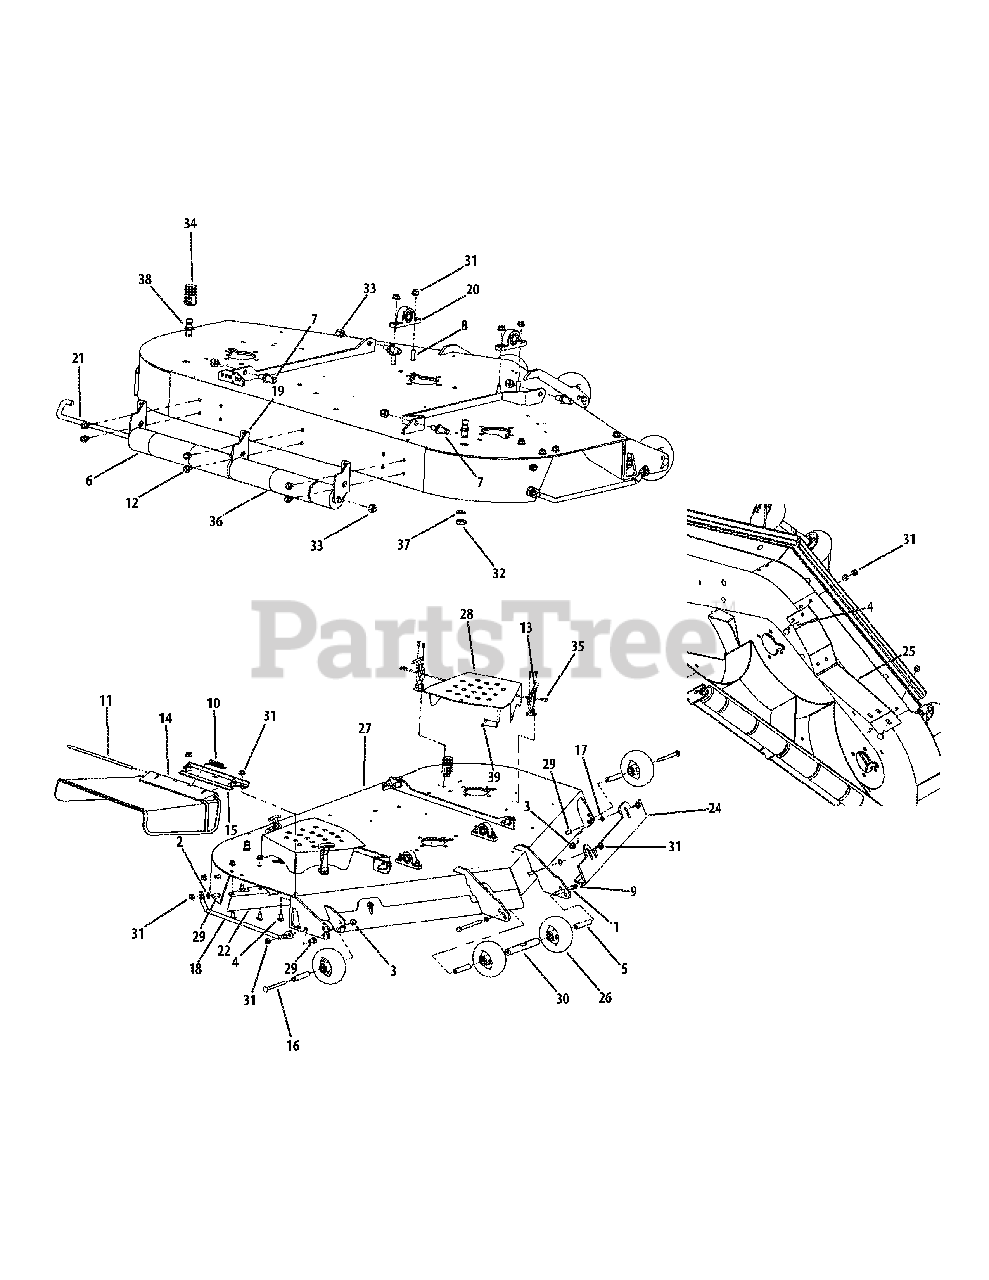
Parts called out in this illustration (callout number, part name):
1	Lock Washer, 3/8
2	Washer, 3/8
3	Flange Lock Hex Nut, 3/8-16
4	Carriage Bolt, 3/8-16 x .75 Lg.
5	Wheel Spacer
6	Grass Catcher Roller
7	Pin, 5/8 Dia. x 1.2 Lg.
8	Carriage Bolt, 3/8-16 x 1
9	Hex Cap Screw, 3/8-16 x 4.50
10	Torsion Spring, 0.4ID x 2.16Lg
11	Chute Deflector Rod
12	Hex Index Washer Screw, 3/8-16, .5
13	T-Handle Latch Draw
14	Chute Deflector
15	Chute Deflector Bracket
16	Carriage Bolt, 3/8-16 x 4.00
17	Push Retainer
18	Finger Guard
19	Grass Catcher Roller Bracket
20	Pillow Block
21	J-Hook w/ Threaded Roller
23	Right Hand Front Adjustment Skirt
24	Left Hand Front Adjustment Skirt
25	Baffle, 60" Adjustment
26	Complete Wheel, 5.00 Dia.
27	60" Deck Assembly
28	Deck Belt Cover
29	Carriage Bolt, 3/8-16 x 1.00
30	Ball Wheel Mounting Shaft
31	Lock Nut, Nylon Insert, 3/8-16
32	Hex Nut, M16-1.5
33	Lock Nut, Nylon Insert, 1/2-13
34	Water Nozzle Adaptor
35	Phillips Head Screw, 10-32
36	Front Roller
37	Lock Washer, 17 x 23.8 x 1.95
38	Deck Water Nozzle
39	Lock Nut, Nylon Insert, 10-32
